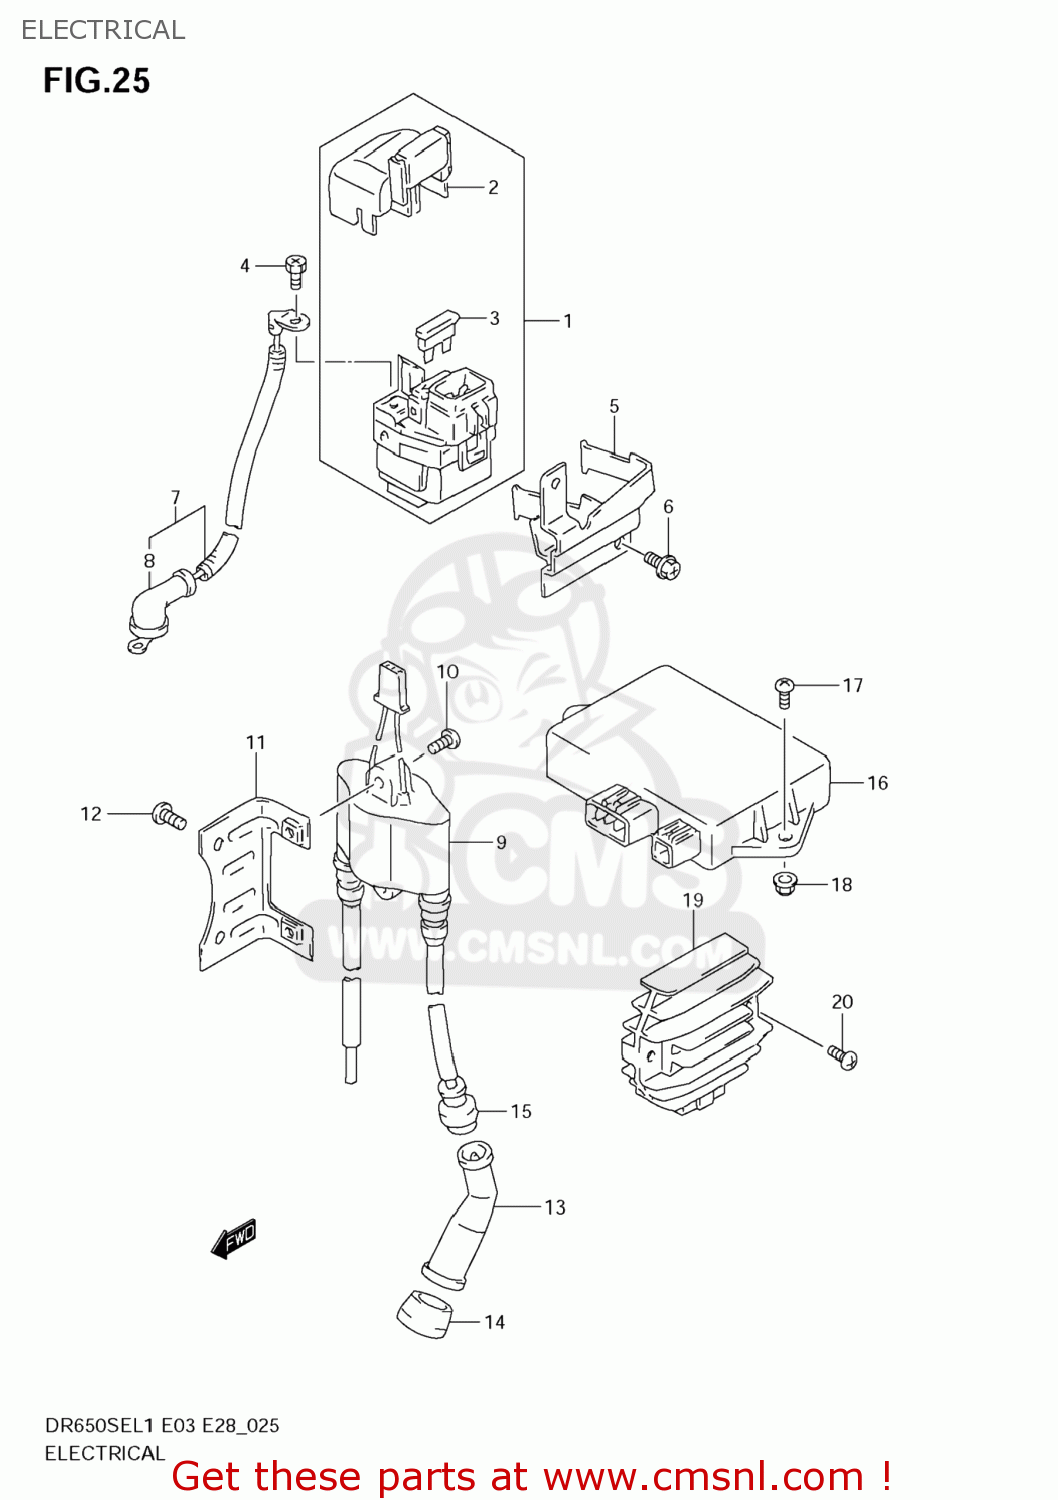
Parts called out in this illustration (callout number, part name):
1	RELAY ASSY,STARTING MOTOR
2	COVER,STARTER RELAY
3	FUSE(30A)
4	SCREW(6X8)
5	BRACKET,STARTING MOTOR RELAY
6	SCREW
7	WIRE,STARTER MOTOR
8	CAP,STARTER MOTOR LEAD
9	COIL ASSY,IGNITION
10	SCREW
11	BRACKET,IGNITION COIL
12	SCREW
13	CAP,SPARK PLUG
14	SEAL,SPARK PLUG
15	SEAL,HIGH TENSION CORD
16	CDI UNIT
17	SCREW
18	NUT
19	RECTIFIER ASSY
20	SCREW
